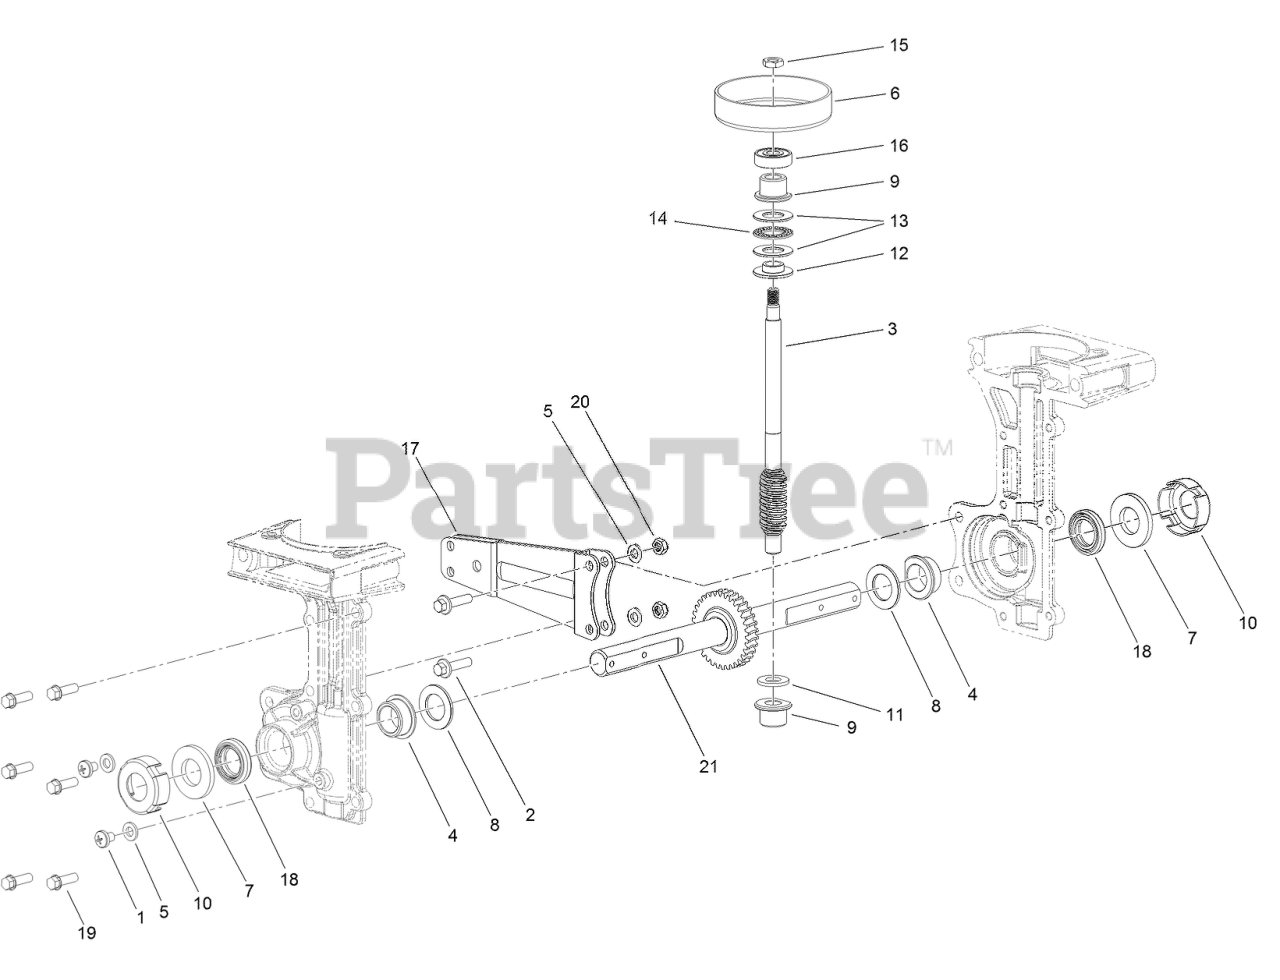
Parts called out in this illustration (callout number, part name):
1	SCREW-PPH
2	SCREW-HHF
3	SHAFT-DRIVE
4	BUSHING-FLANGE
5	WASHER
6	CLUTCH DRUM
7	WASHER-FIBER
8	SHIM-SHAFT, TINE
9	BUSHING-FLANGE
10	CAP-DUST
11	SPACER
12	BEARING-THRUST
13	WASHER-PLAIN
14	BEARING-THRUST
16	BEARING-BALL
17	WHEEL AND DRAG MOUNT
18	SEAL-SHAFT
19	SCREW-HHF
20	NUT-LOCK
21	TINE SHAFT ASM
